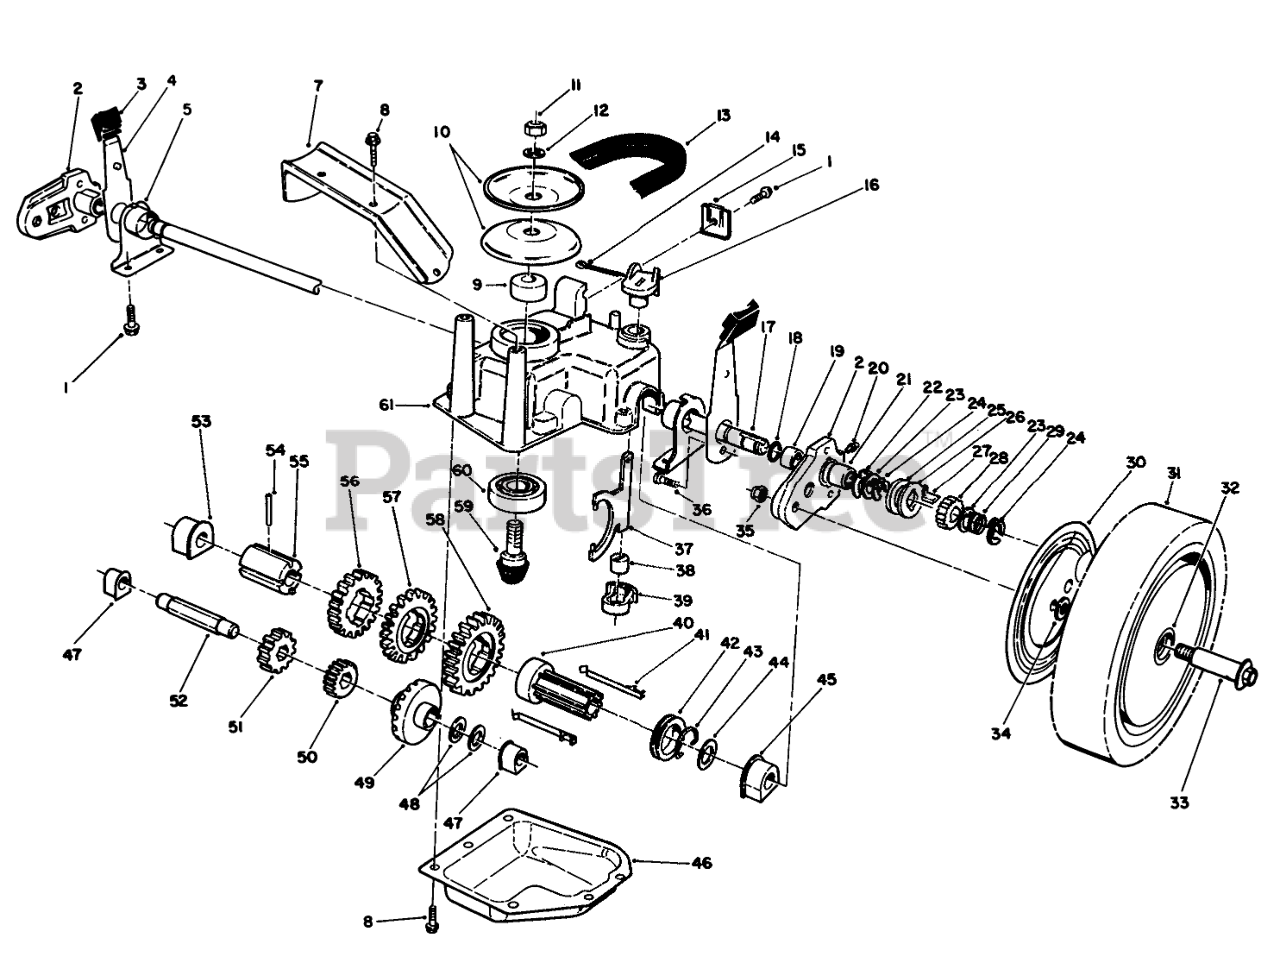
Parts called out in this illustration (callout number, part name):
1	SCREW-HWHTF
2	Pivot Arm Assembly (Incl. Ref. #19-21)
3	KNOB-ARM
4	SPRING ARM ASM
5	CAP-END
7	Bracket-BeltGuide
8	SCREW-HWHTF
9	SPACER
10	Pulley Half
11	NUT-HEX
12	WASHER-FLAT
13	V-BELT
14	PIN-COTTER
15	CABLE CLAMP
16	Lever-Shift
17	SHAFT-OUTPUT
18	O-RING
19	BUSHING
20	FITTING-GREASE
21	BEARING-ROLLER
22	WASHER-ARM, PIVOT
23	WASHER-THRUST, KEYED
24	RING-CLIP, LOCKING
25	RING-FRICTION
26	WASHER-CLUTCH
27	KEY-ROCKING, LH
28	GEAR-PINION
29	SPRING-COMPRESSION
30	WHEEL COVER
31	Wheel Tire & Gear Assy. (Incl. Ref. #32)
32	BUSHING
33	WHEEL BOLT
34	WASHER
35	Nut
36	SCREW-HSH, THREAD FORMING
37	YOKE-SHIFT
38	BUSHING-YOKE
39	RETAINER-FORK, SHIFT
40	Sleeve-Shift Key
41	SHIFT KEY
42	SHIFT COLLAR
43	CLIP-SPRING
44	WASHER-PLAIN
45	BUSHING-OUTPUT
46	Cover-Gearcase
47	BUSHING
48	WASHER-THRUST
49	Gear-Bevel
50	PINION-20T
51	PINION-25T
52	SHAFT-INTERMEDIATE
53	BUSHING
54	PIN-SPRING
55	SLEEVE-GEAR
56	GEAR-39T
57	GEAR-44T
58	GEAR-49T
59	Gear-Pinion
60	BEARING-BALL
61	CASE-GEAR, UPPER
